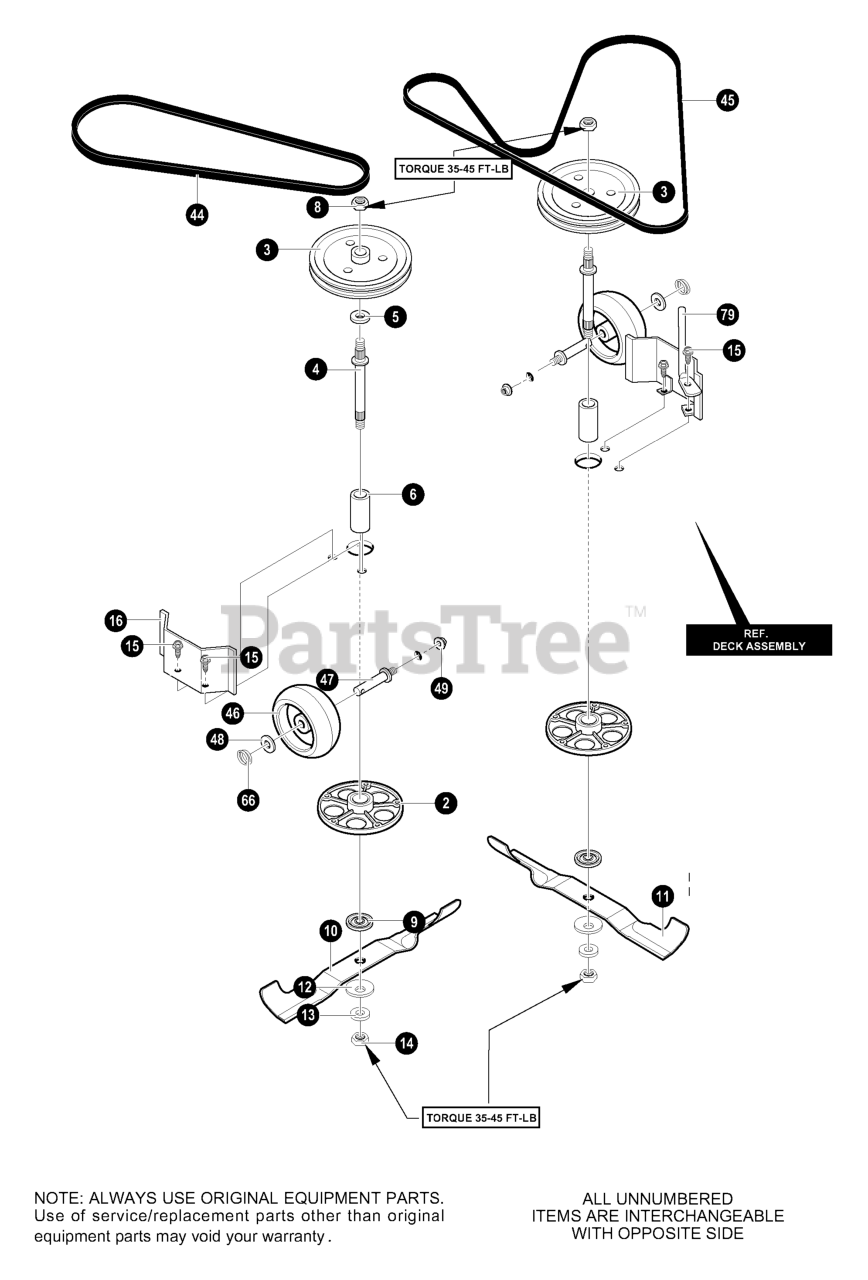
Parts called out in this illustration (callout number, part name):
2	ASSEMBLY, JACKSHAFT HOUSING
3	PULLEY, DECK
4	JACKSHAFT
5	WASHER, FLAT
6	SPACER, .625X.875X1.91
8	NUT, 9/16-18
9	ADAPTER, DECK/BLADE 40"
10	BLADE, LH
11	BLADE, RH
12	WASHER,BELLVILLE
13	WASHER, FLAT
14	NUT, 9/16-18
15	SCREW,3/8-16X1.00
16	COVER PULLEY
44	BELT, V 46.5LG
45	BELT, DECK
46	GAUGE WHEEL
47	BOLT, SHOULDER
48	WASHER, FLAT
49	NUT, 3/8-16
66	PIN, CIRCLE
79	ROD, BELT GUIDE
